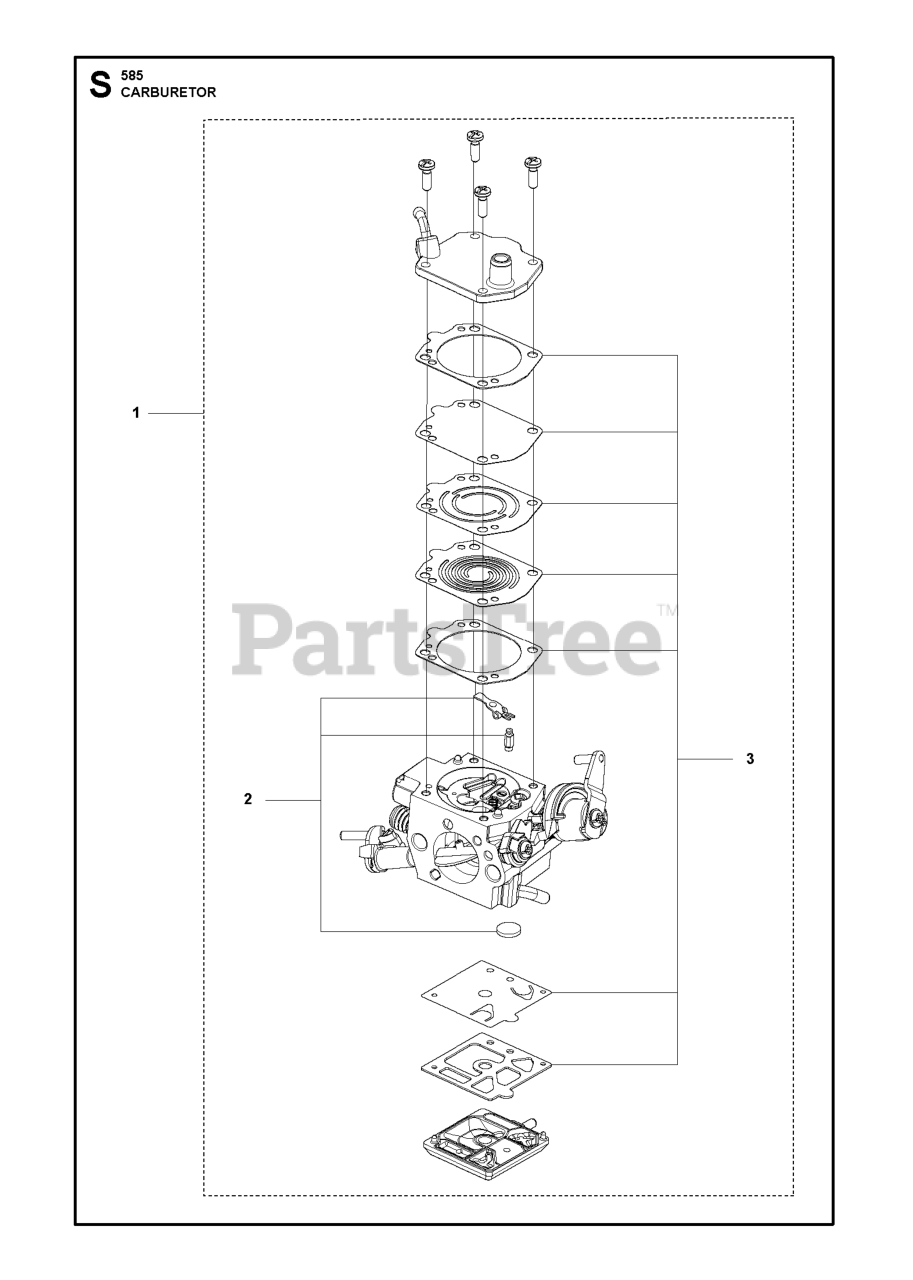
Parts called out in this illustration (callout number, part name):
1	CARBURETTOR HDA-351B
2	REPAIR KIT 592/585 CARB
3	GASKET KIT 592 AND 585 CARB IN
